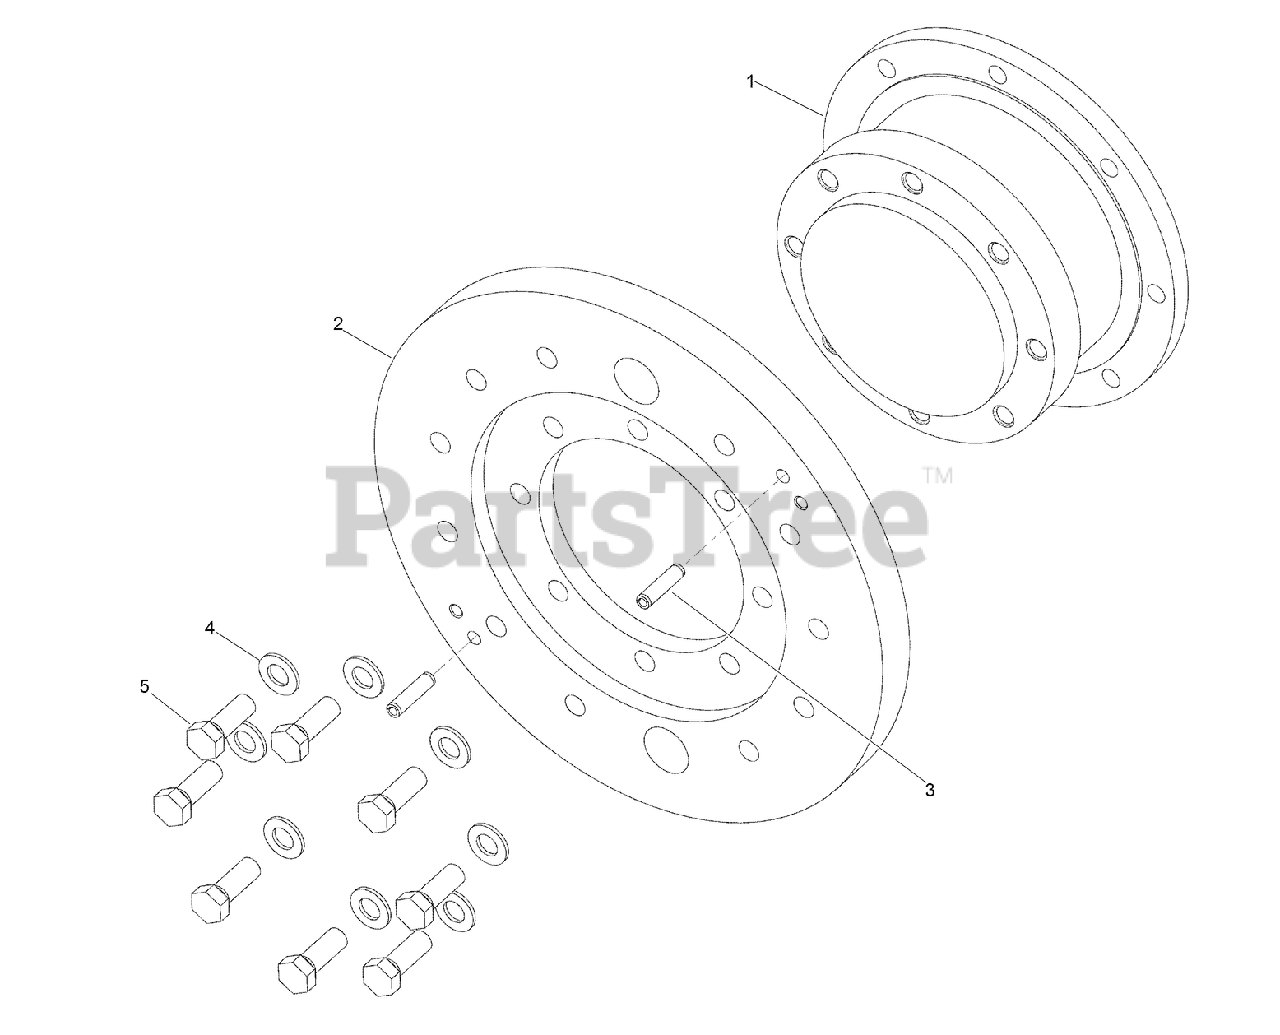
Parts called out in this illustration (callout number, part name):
1	HUB - Model 82N Non-Powered
2	PLATE - Hub Mount
3	PIN - Slid Spring, .500 x 2.00 in C-Z
